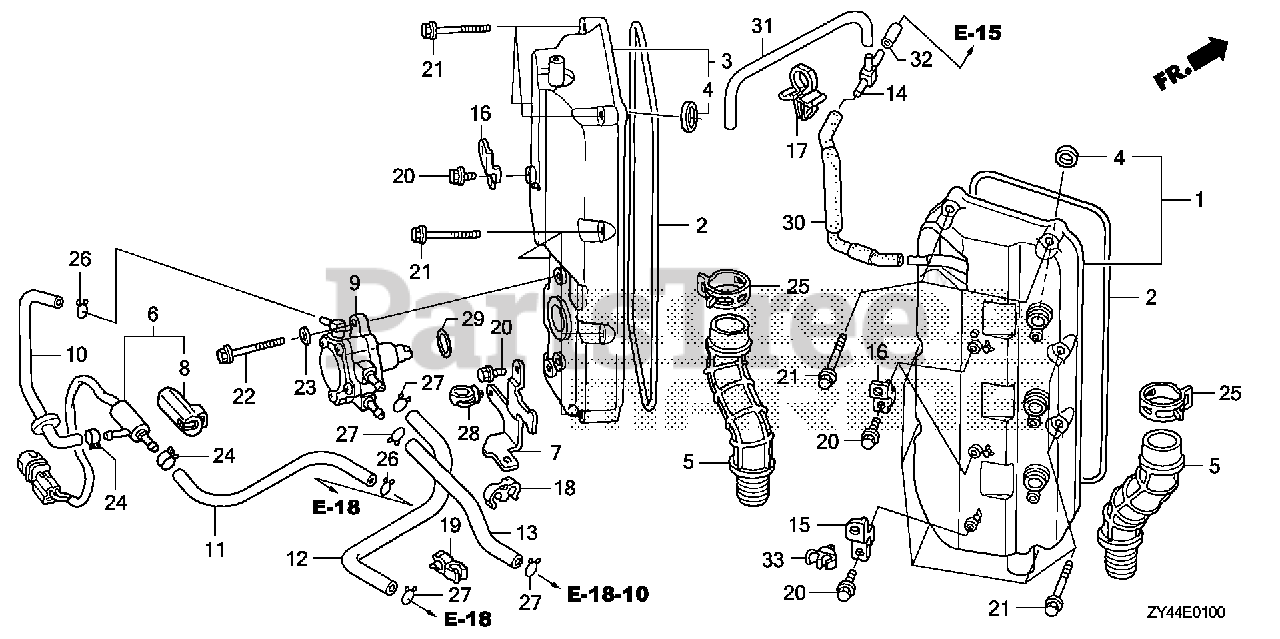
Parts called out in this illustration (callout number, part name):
1	COVER, R. CYLINDER HEAD *NH8* (DARK GRAY)
2	GASKET, HEAD COVER
3	COVER, L. CYLINDER HEAD *NH8* (DARK GRAY)
4	SEAL, SPARK PLUG TUBE (NOK)
5	TUBE, OIL
6	VALVE ASSY., SOLENOID
7	BRACKET, SOLENOID VALVE
8	GROMMET, SOLENOID VALVE
9	PUMP ASSY., FUEL (MSDS)
10	TUBE D, FUEL
11	TUBE E, FUEL
12	TUBE F, FUEL
13	TUBE G, FUEL
13	TUBE, FUEL (7.3X380)
15	BRACKET, CLIP B
16	BRACKET C, HARNESS CLIP
17	CLIP A, WIRE
18	CLIP, SENSOR HOSE
19	CLIP, SHIFT WIRE
20	BOLT, FLANGE (6X14) (CT200)
21	BOLT, FLANGE (6X35)
22	BOLT, FLANGE (8X32)
23	WASHER, PLAIN (8MM)
24	CLAMP, TUBE (D10.7)
25	CLAMP, TUBE (D32.5)
26	CLIP, TUBE (B10)
27	CLIP, TUBE (B12)
28	CLIP, HARNESS
29	O-RING (37X2.4) (ARAI)
30	TUBE A, BREATHER
31	TUBE B, BREATHER
32	TUBE C, BREATHER
33	CLIP D, WASHER TUBE
